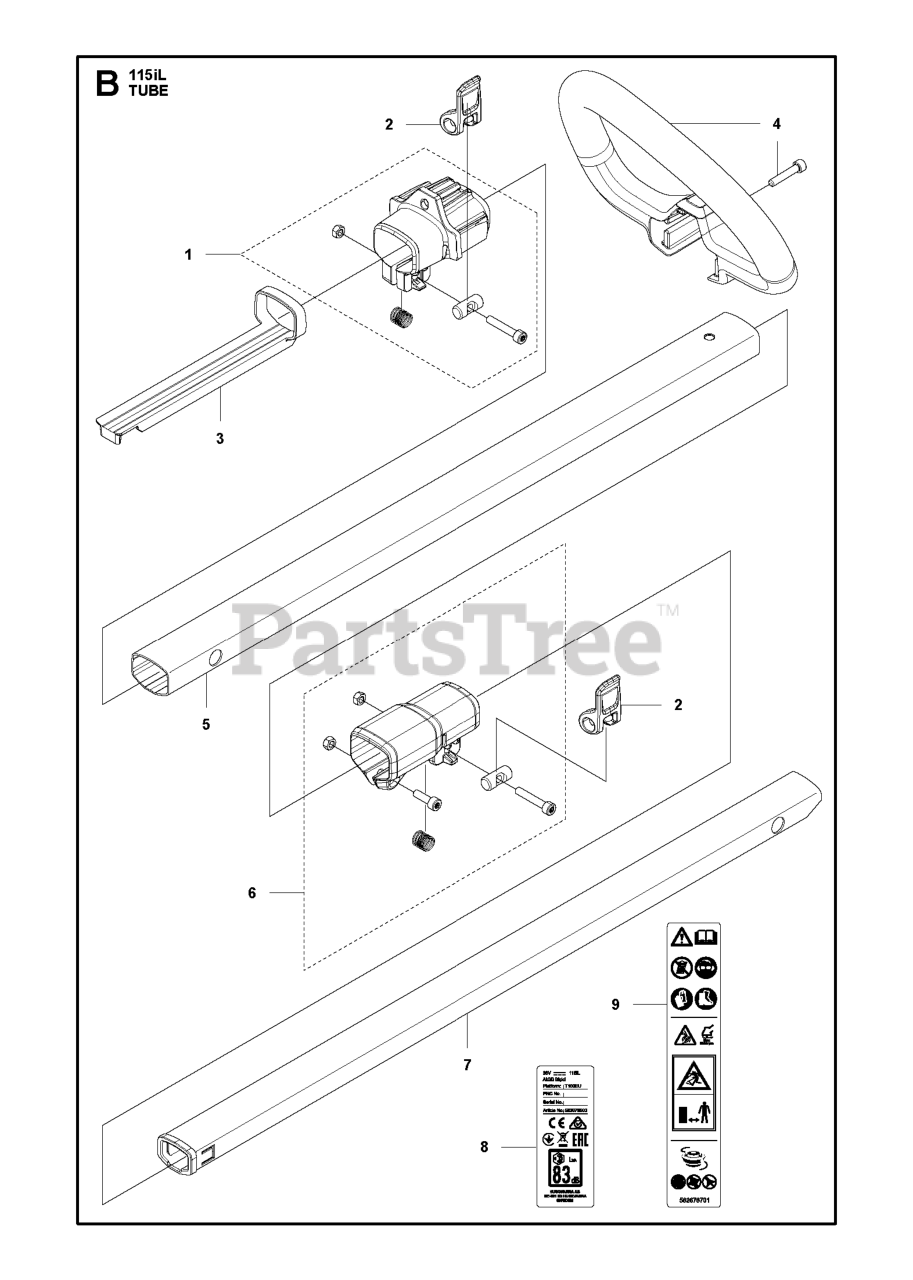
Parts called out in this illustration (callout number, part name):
1	COUPLING ,FRONT HANDLE ASSY
2	LEVER COUPLING
3	SPACER FRONT HANDLE
4	FRONT HANDLE
6	COUPLING ,TUBE COUPLING ASSY
7	TUBE ASSY SMALL TUBE ASSEMBLY
